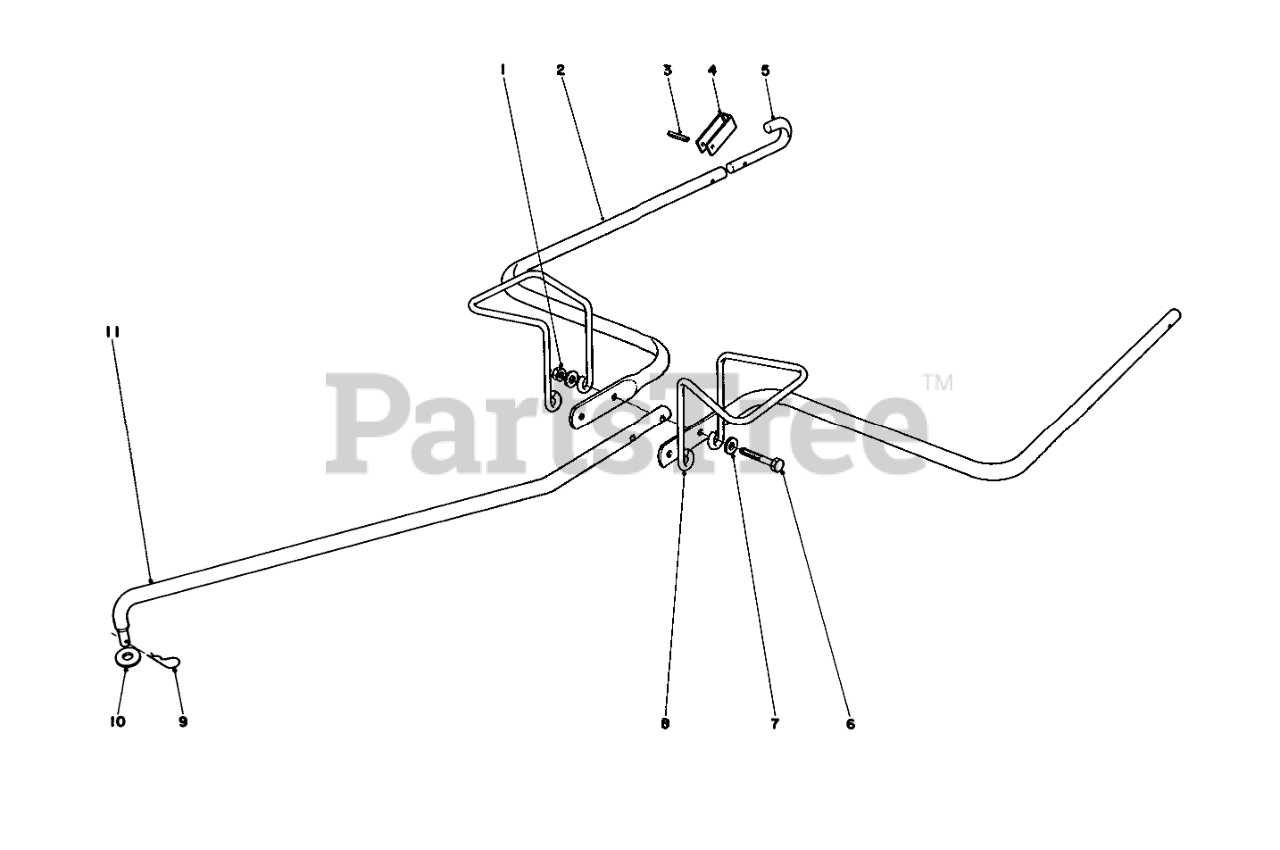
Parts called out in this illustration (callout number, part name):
2	HITCH ARM
3	PIN-ROLL, SLOT
4	HITCH LOCK
5	HOOK HITCH ARM
6	SCREW-HH
7	WASHER-FLAT
8	Support Bag
9	PIN-COTTER
10	PUSH NUT
11	POLE HITCH
